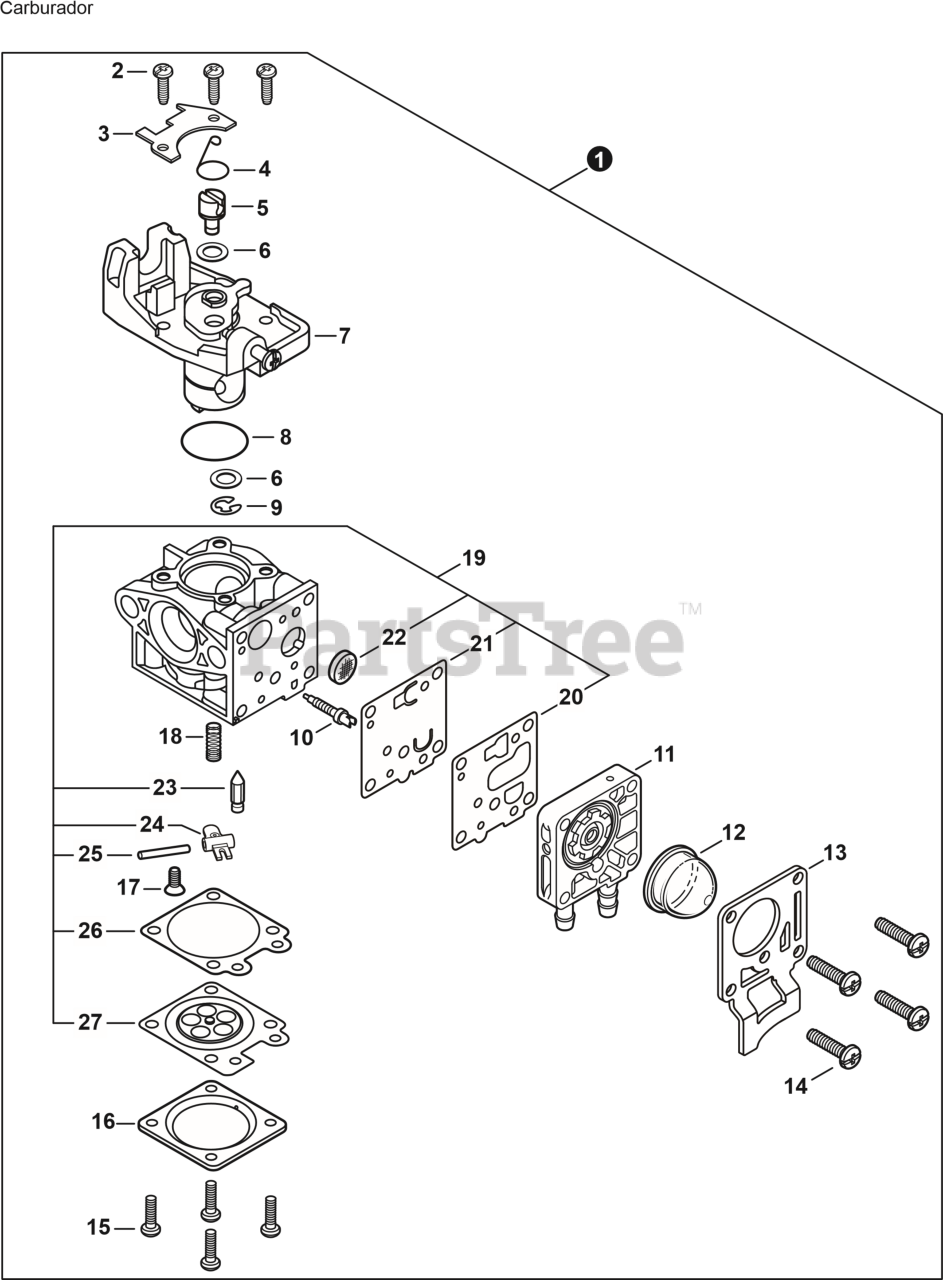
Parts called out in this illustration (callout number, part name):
1	CARBURETOR - WYG-11A
7	THROTTLE VALVE ASSY
10	NEEDLE, MIXTURE
11	BODY ASSY, PUMP
12	BULB, PURGE
13	COVER, FUEL PUMP
16	COVER, METERING DIAPHRAGM
19	REPAIR KIT, CARBURETOR
20	GASKET, FUEL PUMP
21	DIAPHRAGM, FUEL PUMP
22	SCREEN, FUEL INLET
23	VALVE, INLET NEEDLE
24	LEVER, METERING
25	PIN, METERING LEVER
26	GASKET, METERING DIAPHRAGM
27	DIAPHRAGM, METERING
